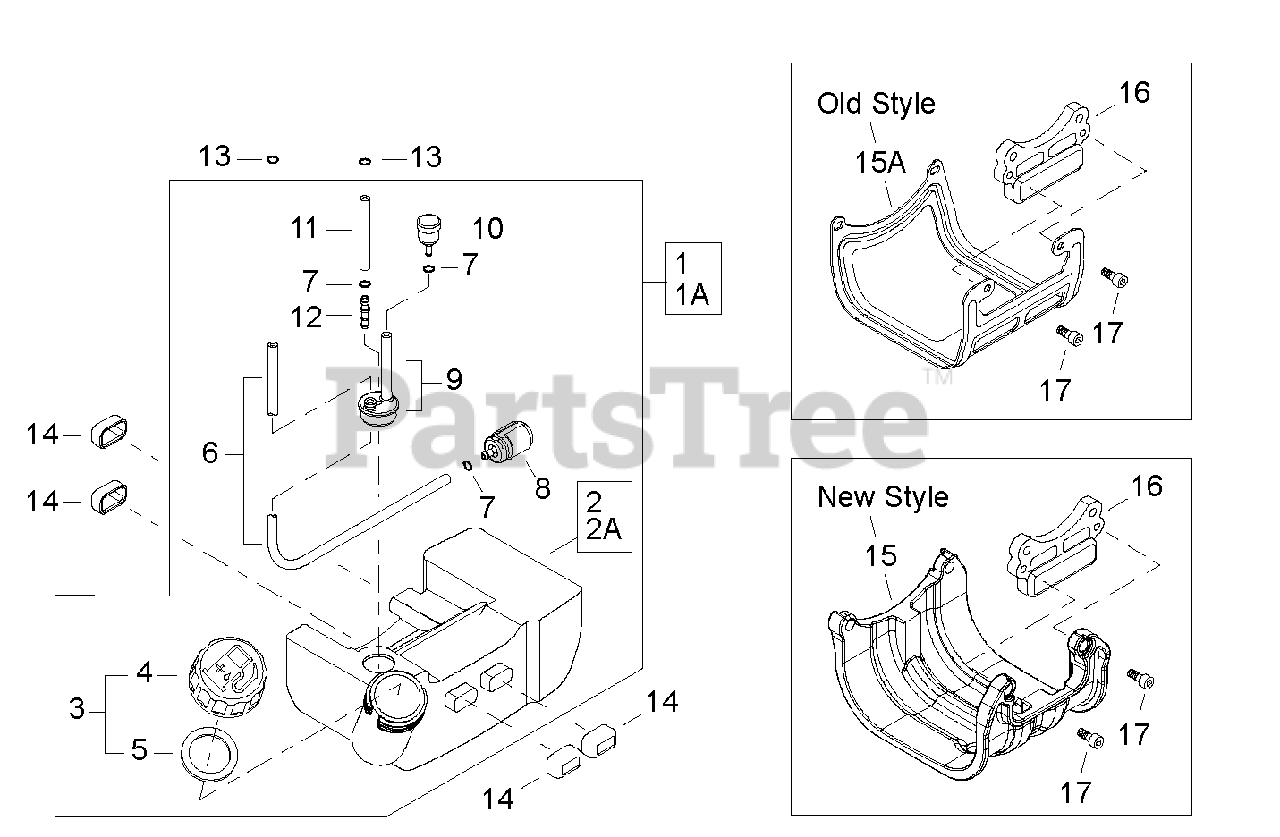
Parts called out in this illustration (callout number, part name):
1	TANK ASSY, FUEL
1A	TANK ASSY, FUEL
2	TANK, FUEL
2A	TANK, FUEL
3	CAP ASSY, FUEL
4	CAP, FUEL
5	GASKET, FUEL CAP
6	PIPE, FUEL
7	CLIP Ø6
8	FILTER, FUEL
9	GROMMET, FUEL W/VENT PIPE
10	VENT ASSY
11	PIPE, FUEL RETURN
12	CONNECTOR, PIPE
13	CLIP Ø6
14	CUSHION, FUEL TANK
15	GUARD, PLASTIC FUEL TANK
15A	GUARD, METAL FUEL TANK
16	BRACKET, FUEL TANK
17	BOLT M5×16
